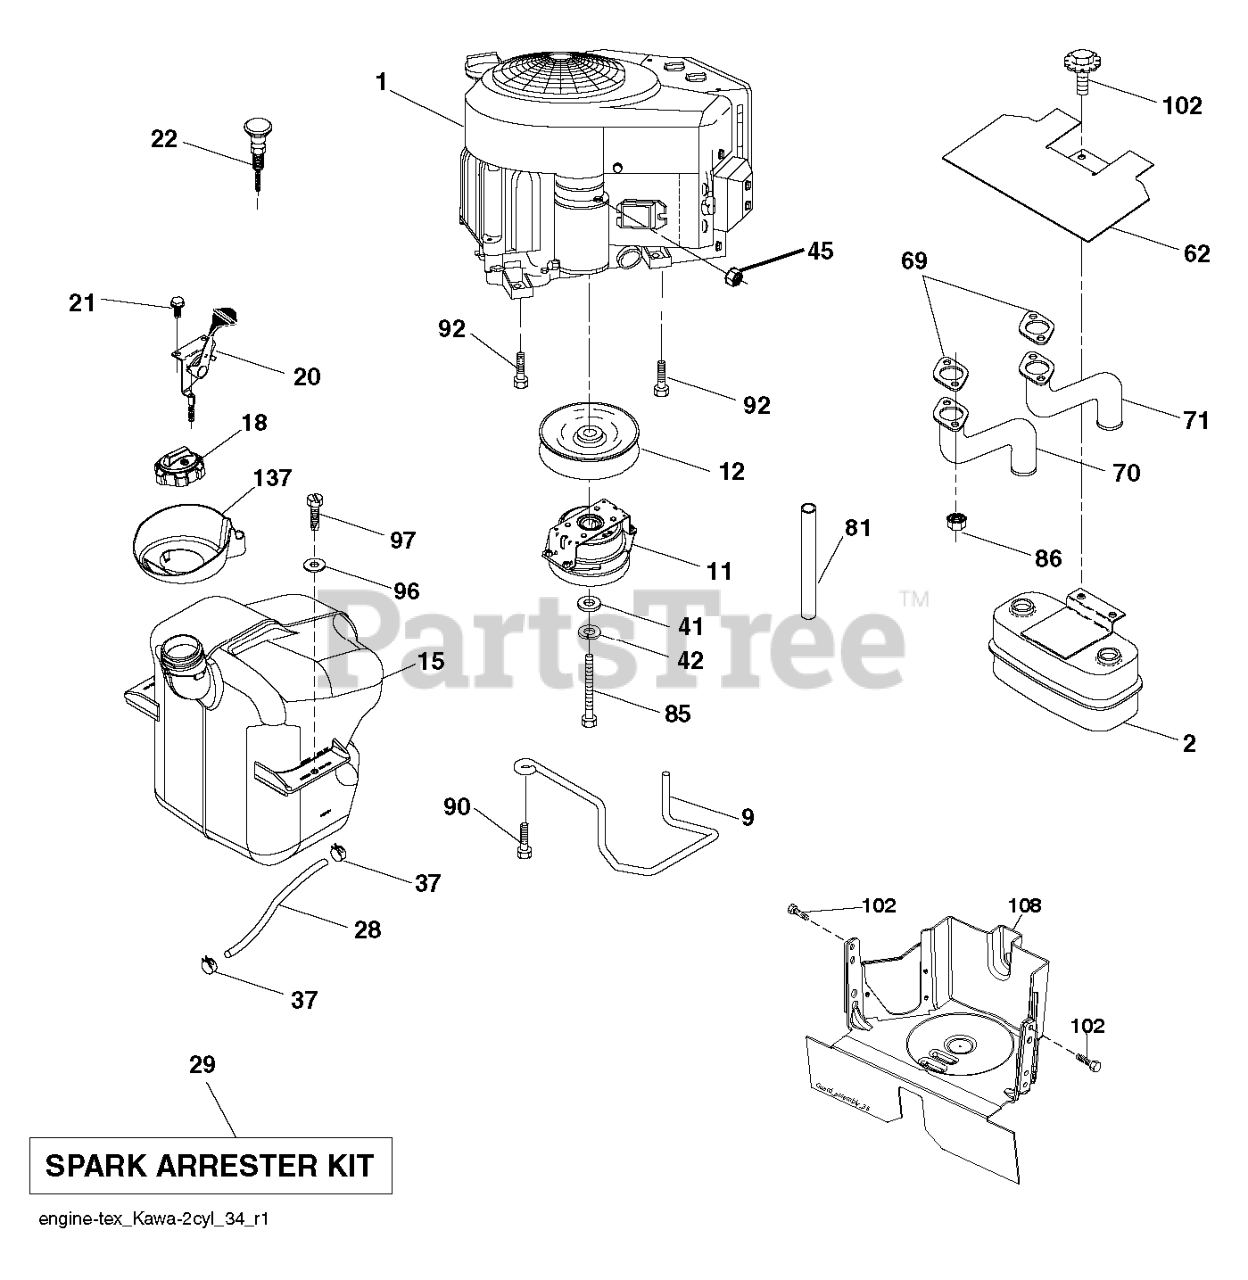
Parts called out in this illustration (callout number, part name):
2	MUFFLER.ASM.TWN.EXTNDED.DFLCTR
9	KEEPER BELT ENGINE
11	CLUTCH.ELECTRIC.LT.48"*
12	PULLEY.ENGINE.TUFFTORQ
15	FUEL TANK TANK. ASSEMBLY. EXTE
18	CAP.ASM.FUEL.2.25"TOP.TURN
20	CONTROL.THROTTLE.COBRA.BLACK
21	SCREW.#10 X 0.750.BOS
22	CONTROL, CHOKE
28	LINE.FUEL.20
29	KIT.SPARK ARRESTOR 794945 B&S
37	HOSE CLAMP
42	LOCKWASHER
45	NUT
62	SHIELD.HEAT.MUFFLER
70	TUBE.EXHAUST.LH.FR961/FR730
71	TUBE.EXHAUST.RH.FR961/FR730
81	TUBE, DRAIN OIL ASM.
85	BOLT HEX 7/16-20X4-1/4"
86	NUT.HEX.FLANGE.TOPLOCK
87	BOLT.5/16-18UNCX3/4 W/SEMS.BLK
90	SCREW 3/8-16X1
92	SCREW 3/8-16X1
96	WASHER
97	SCREW HEXWSHR 1/4-20X3/4
102	SCREW 5/16-18X1
108	COVER PULLEY
